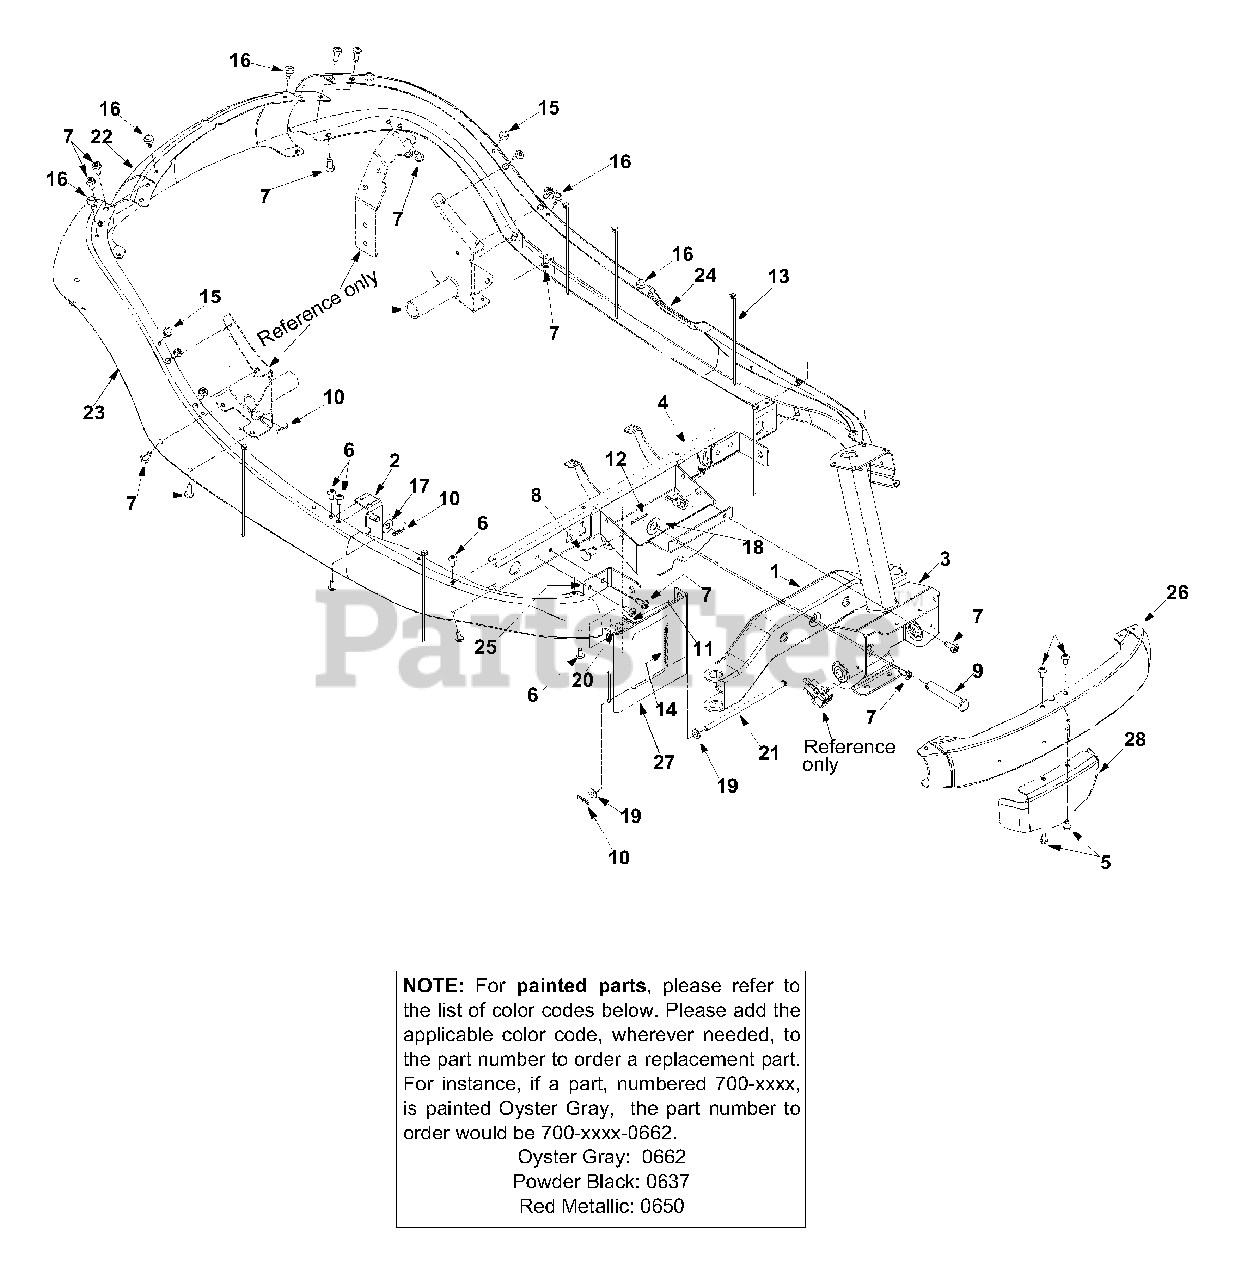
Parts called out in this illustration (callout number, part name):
5	TT screw 1/4-20 x 0.5"
6	AB Screw 1/4-14 x 0.625"
7	TT Screw 5/16-18 x 0.75"
8	Clevis Pin
11	Hairpin Clip
14	Extension Spring
15	Rubber Bumper
16	Bumper
17	Flat Washer
